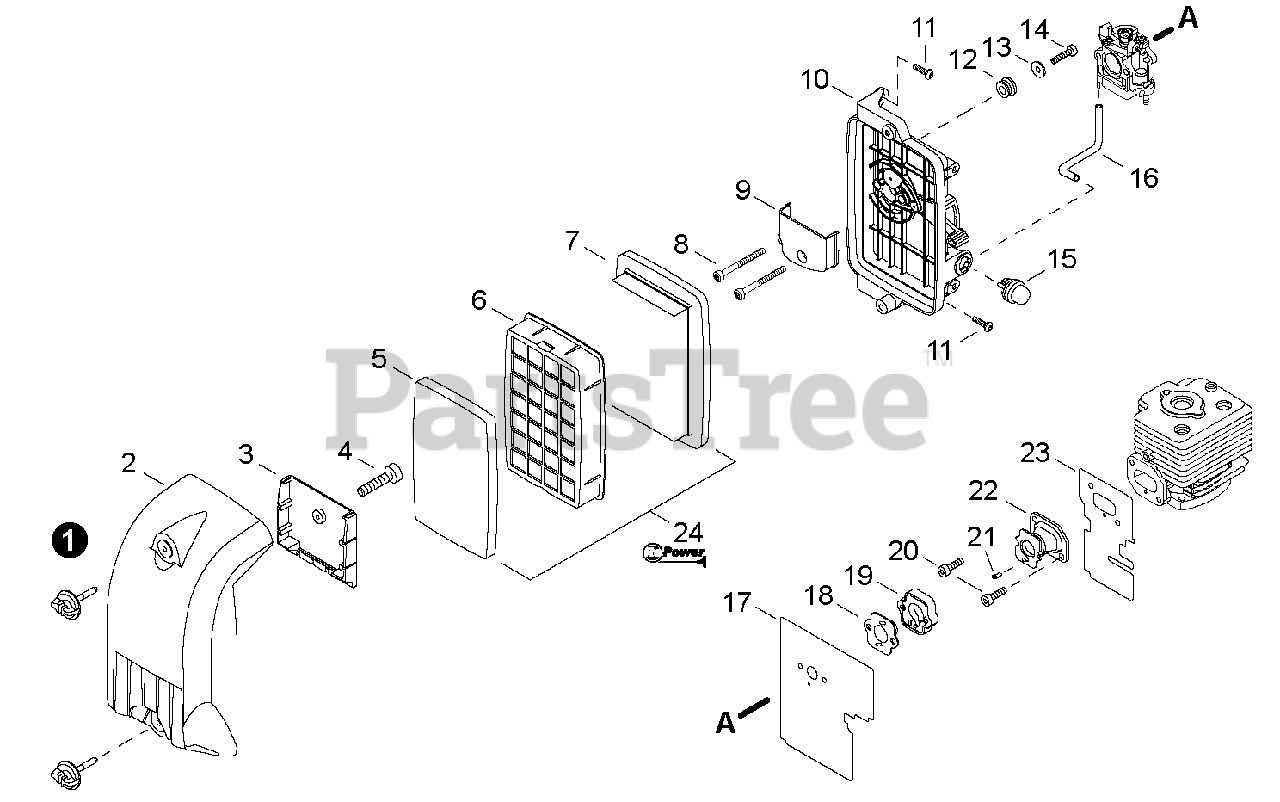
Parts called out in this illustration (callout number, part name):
1	THUMBSCREW
2	COVER, AIR FILTER
3	SUPPORT, PRE-FILTER
4	BOLT, TORX 4×12
5	PRE-FILTER, FOAM
6	RETAINER, PRE-FILTER
7	FILTER, AIR
8	BOLT, TORX 5×55
9	PLATE, PREVENT
10	CASE, AIR FILTER
11	BOLT, TORX 5×20
12	GUIDE, CABLE
13	WASHER 5.5×16×0.8
14	BOLT, TORX 5×16
15	BULB, PURGE
16	PIPE, PURGE 2.5×5×140
17	HEAT SHIELD, INTAKE
18	GASKET, INTAKE
19	ADAPTOR, INTAKE
20	BOLT, TORX 5×12
21	COLLAR Ø3.2×6.5
22	BELLOWS, INTAKE
23	HEAT SHIELD, INTAKE
24	TUNE-UP KIT - REPOWER
